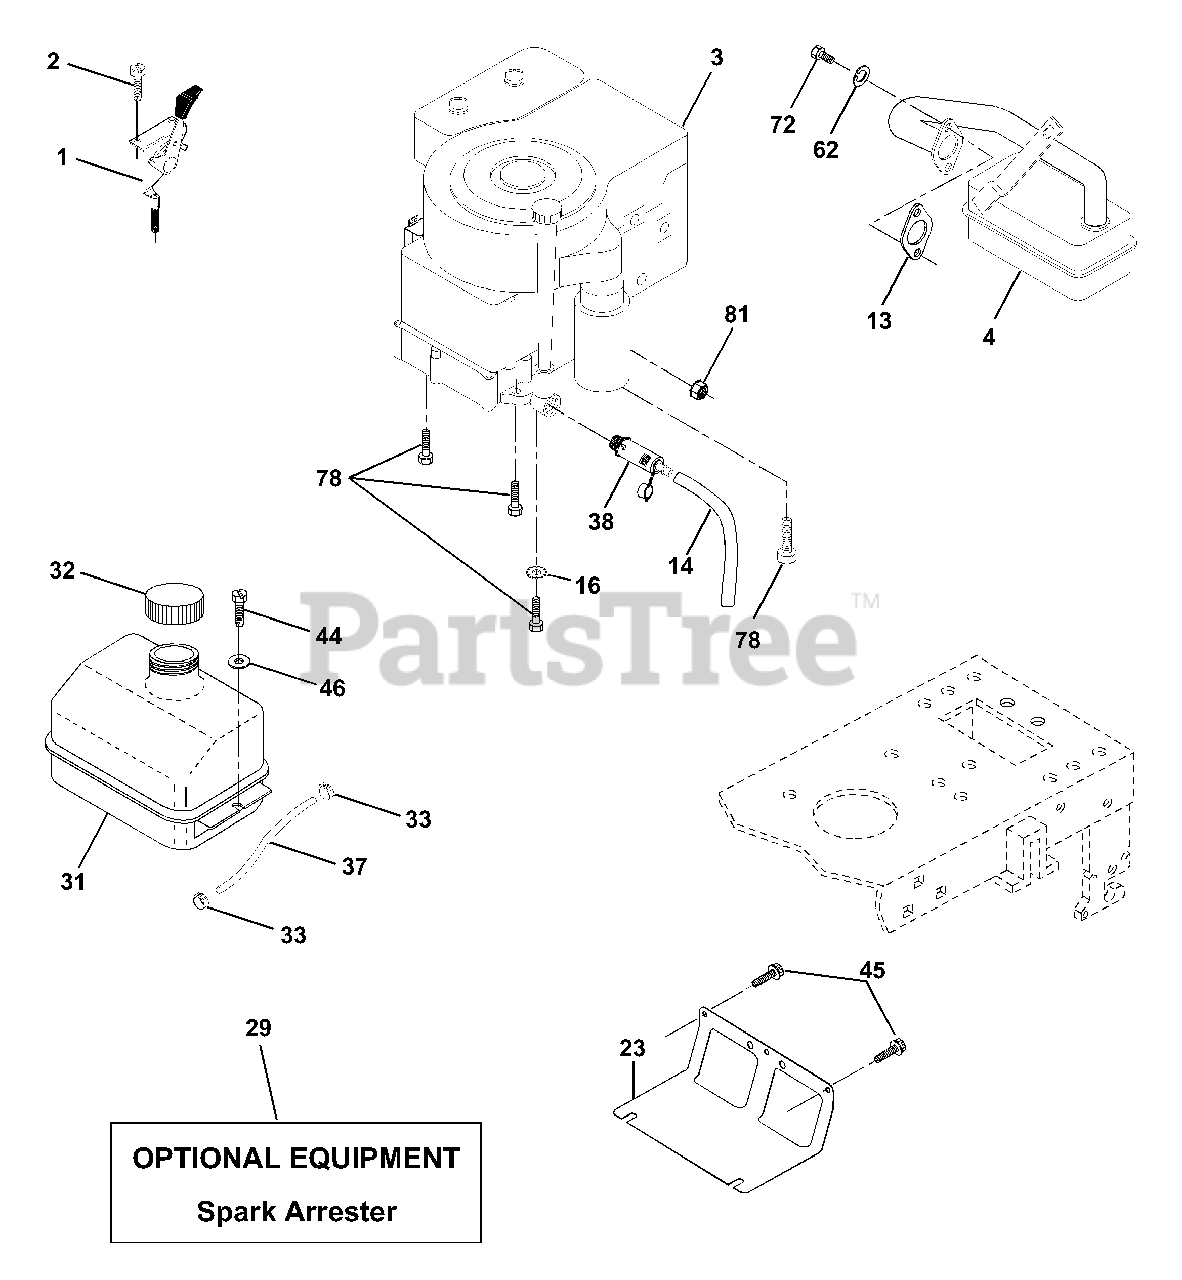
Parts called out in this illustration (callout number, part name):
1	Control Th/ch Flag
2	Screw Hex Thd Cut 1/4-20x5/8 T
4	Muffler Exhaust B&S Lc
13	Gasket Eng 1 313 Id Tin Plated
14	Tube Drain Oil Easy
16	Washer Lock Ext Tooth 3/8
23	Shield BRN/DBR Guard
29	Kit Spark Arrestor (Flat Scrn)
31	Tank Fuel Front
32	Cap Asm Fuel
33	Clamp Hose
37	Line Fuel 20"
38	Plug Drain Oil Easy
44	Screw Thdrol 1/4-20 x 3/4
45	Screw Hex Wsh Thdrol 3/8-16
46	Washer 9/32 X 7/8 X 16 Ga
62	Washer Lock Hvy Hlcl Spr
72	Screw Hexcap 5/16-18 x 3/4
78	Screw 3/8-16 x 1-1/4
81	Nut Keps Hex 1/4-20 Unc
